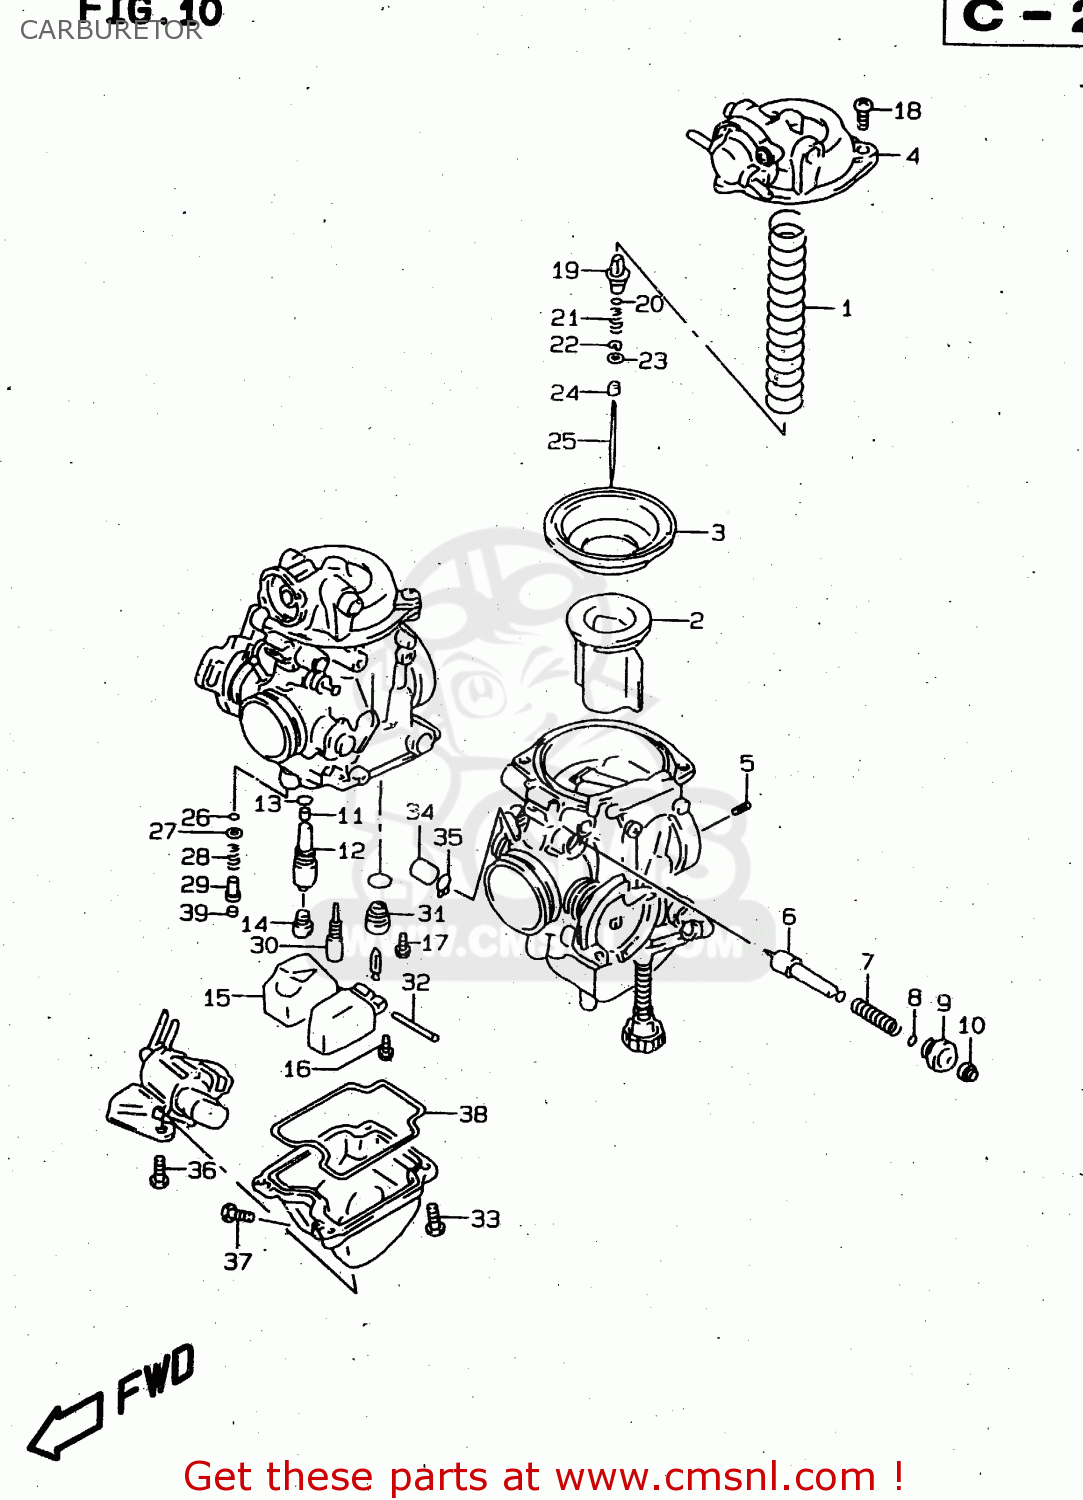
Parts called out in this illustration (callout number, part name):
1	SPRING
2	VALVE,PISTON
3	DIAPHRAGM
4	COVER ASSY,DIAPHRAGM,L
5	JET,POWER(150)
6	PLUNGER ASSY
7	SPRING
8	O RING
9	GUIDE SCREW,PLUNGER
10	CAP,STARTER VALVE
11	JET,NEEDLE(P-0)
12	HOLDER,JET
13	O RING
14	JET,MAIN(115)
15	FLOAT ASSY
16	SCREW
17	SCREW
18	SCREW
19	HOLDER
20	O RING(D:1.9,ID:4.8)
21	SPRING
22	E RING,MULTIPLE JET NOZZLE
23	WASHER
24	RING
25	NEEDLE,JET(5DH23-53-3)
26	O RING,PILOT AIR SCREW
27	WASHER
28	SPRING,THROTTLE SCREW
29	ADJUSTER
30	JET,PILOT(20)
31	VALVE ASSY,NEEDLE
32	PIN,FLOAT
33	SCREW
34	CAP
35	CLIP
36	SCREW
37	SCREW,DRAIN
38	GASKET (NAS)
39	PLUG
